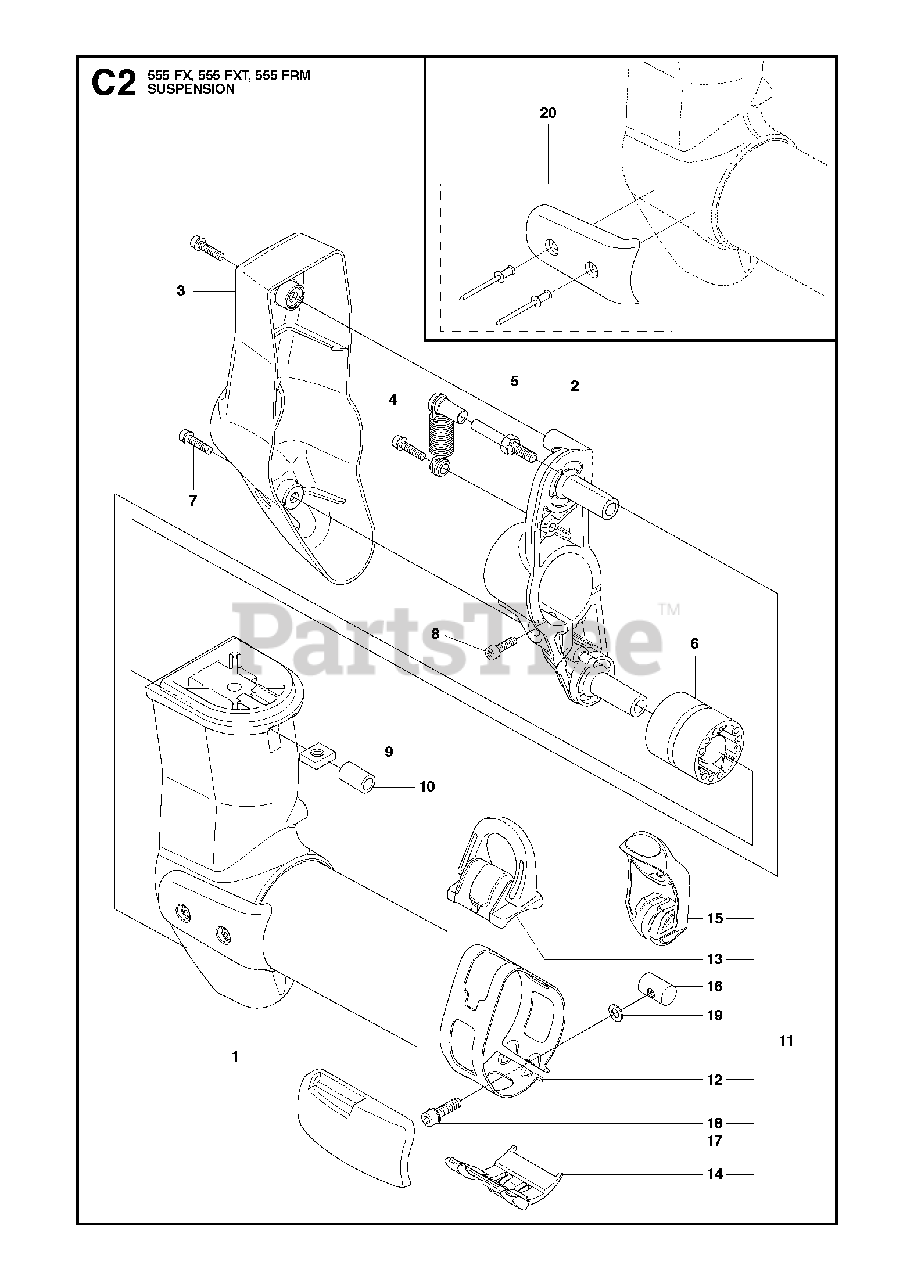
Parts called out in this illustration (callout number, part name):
1	SUSPENSION
5	PARALLEL PIN
6	ANTIVIBE ELEMENT
7	SCREW IHSCFM
11	LOOP
12	BAND
13	LOOP
14	GUIDE RAIL
15	LEVER
16	NUT
17	WEAR PROTECTION
18	SCREW
19	WASHER 5.3X12
20	WEAR PROTECTION KIT
